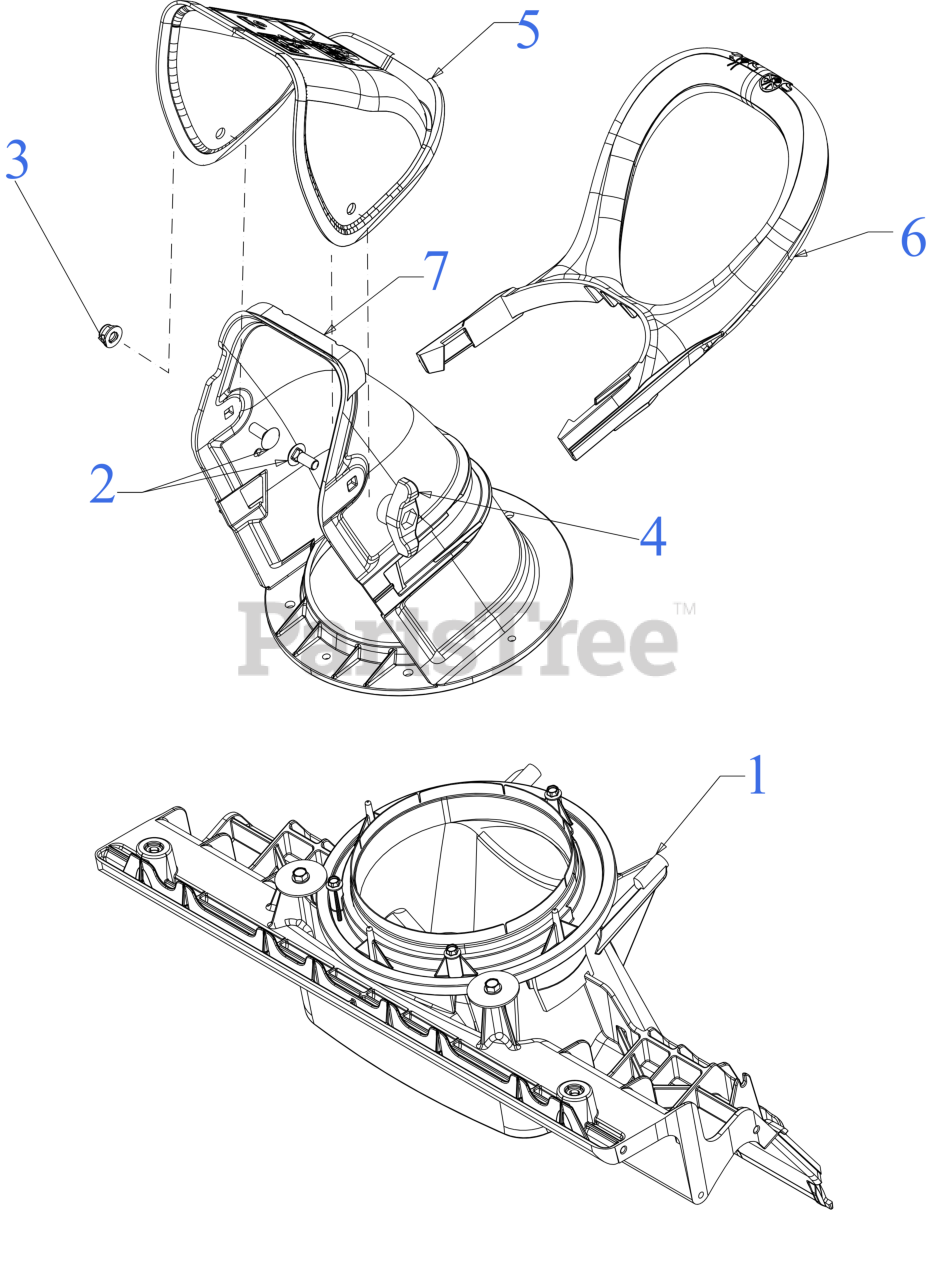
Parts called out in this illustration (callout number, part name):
1	CHUTE ADAPTER ASSEMBLY
2	CARRIAGE BOLT 5/16-18 x .75
3	FLANGE LOCK NUT 5/16-18
4	WING KNOB 5/16-18
5	UPPER CHUTE (W/LBL MANUAL TILT)
6	CHUTE HANDLE
7	LOWER CHUTE 6.5"
